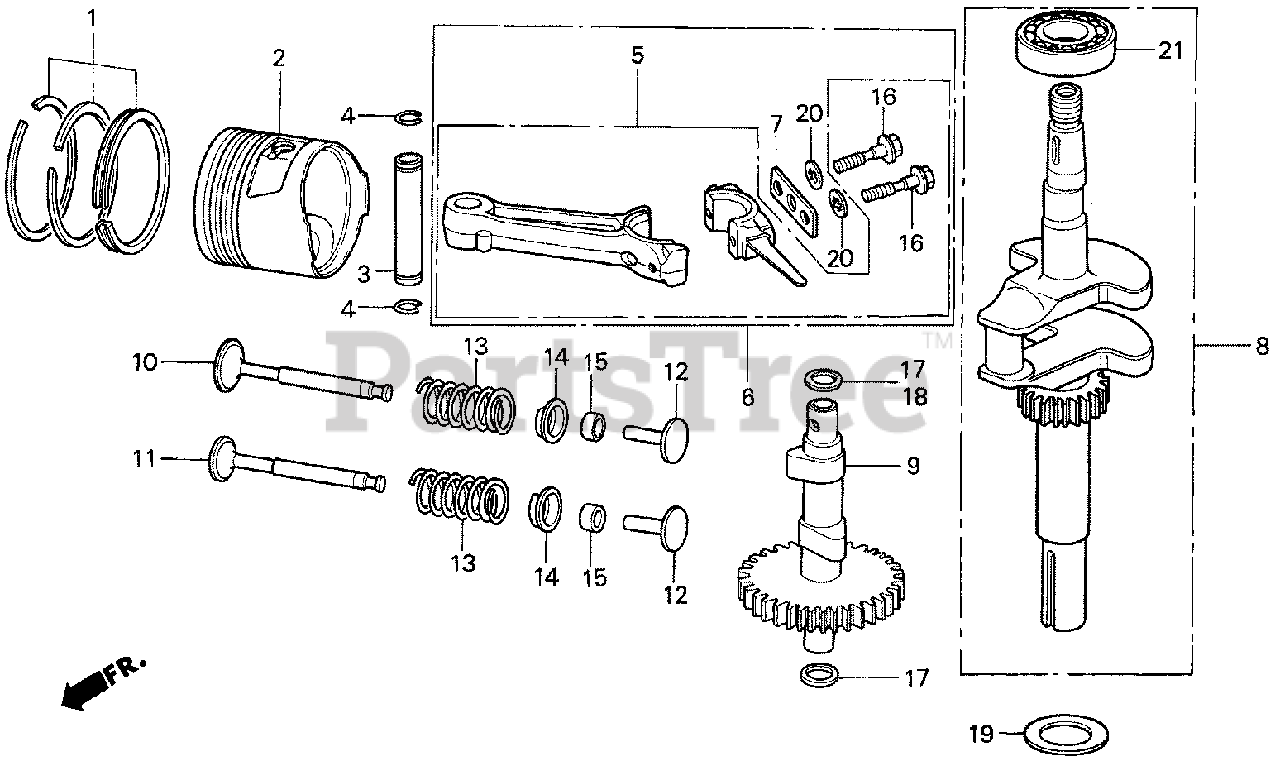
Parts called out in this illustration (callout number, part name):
1	RING SET, PISTON (STD) (TEIKOKU)
1	RING SET, PISTON (OVER SIZE)
2	PISTON
2	PISTON (STD)
2	PISTON (OVER SIZE) (0.25)
2	PISTON (OVER SIZE) (0.50)
2	PISTON (OVER SIZE) (0.75)
3	PIN, PISTON
4	CLIP, PISTON PIN (10MM)
5	ROD ASSY., CONNECTING (STD)
5	ROD ASSY., CONNECTING (UNDER SIZE)
6	ROD ASSY., CONNECTING (STD)
6	ROD ASSY., CONNECTING
6	ROD ASSY., CONNECTING Use up to Engine SN 1443595.
7	WASHER, CONNECTING ROD (NOT AVAILABLE)
8	CRANKSHAFT
10	VALVE, IN.
11	VALVE, EX.
12	LIFTER, VALVE
13	SPRING, VALVE
14	RETAINER, VALVE SPRING (NOT AVAILABLE)
15	ADJUSTER, TAPPET CLEARANCE (3.15)
15	ADJUSTER, TAPPET CLEARANCE (3.25)
15	ADJUSTER, TAPPET CLEARANCE (3.34)
15	ADJUSTER, TAPPET CLEARANCE (3.43)
15	ADJUSTER, TAPPET CLEARANCE (3.52)
15	ADJUSTER, TAPPET CLEARANCE (3.61)
15	ADJUSTER, TAPPET CLEARANCE (3.72)
16	BOLT, CONNECTING ROD
17	WASHER, THRUST (10MM)
17	WASHER, THRUST (9.9MM)
18	WASHER, THRUST (9.9MM)
19	WASHER, THRUST (20MM)
20	WASHER, LOCK
21	BEARING, RADIAL BALL (6203)
